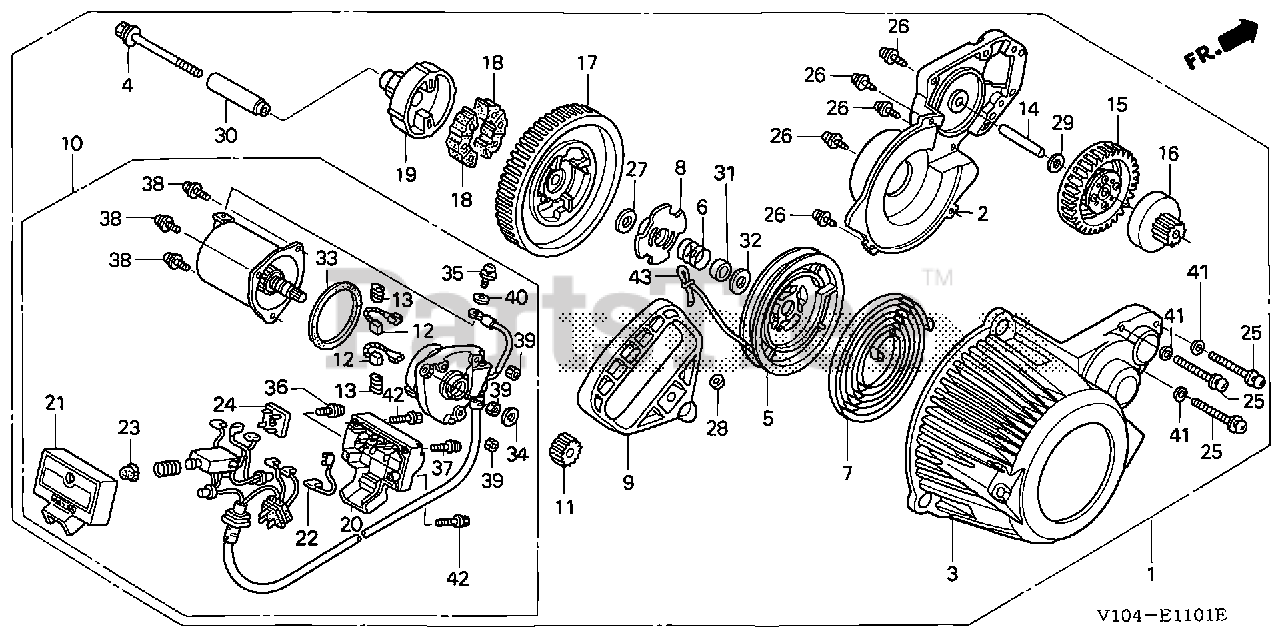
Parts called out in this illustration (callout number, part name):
1	STARTER ASSY., RECOIL
2	COVER, GEAR
3	CASE SET, STARTER
4	BOLT, CENTER (8MM)
5	REEL, RECOIL STARTER
6	SPRING, FRICTION
7	SPRING, RECOIL STARTER
8	GUIDE, RATCHET
9	GRIP, STARTER
10	STARTER MOTOR UNIT (NOT AVAILABLE)
12	BRUSH Use from Engine SN 2056820.
13	SPRING, BRUSH RETURN Use from Engine SN 2056820.
14	SHAFT, GEAR
19	CAM, DRIVE
20	COVER Use from Engine SN 2056820.
22	SUB-WIRE Use up to Engine SN 2056819.
23	CAP Use up to Engine SN 2056819.
24	DIODE Use up to Engine SN 2056819.
25	SCREW-WASHER (5X30)
26	SCREW-WASHER (4X16)
27	WASHER C (11MM)
29	WASHER (8MM)
30	COLLAR (1.8X51.4)
31	COLLAR (2.15X9.4)
32	WASHER B (16MM)
33	GASKET Use from Engine SN 2056820.
34	OIL SEAL Use up to Engine SN 2056819.
35	SCREW, PAN (5X10)
36	SCREW-WASHER (4X20)
37	SCREW-WASHER (4X30)
38	SCREW-WASHER (5X14)
39	NUT, HEX. (5MM)
40	WASHER, SPRING (5MM)
41	WASHER E (5MM)
42	BOLT, FLANGE (6X40)
43	ROPE, RECOIL STARTER
